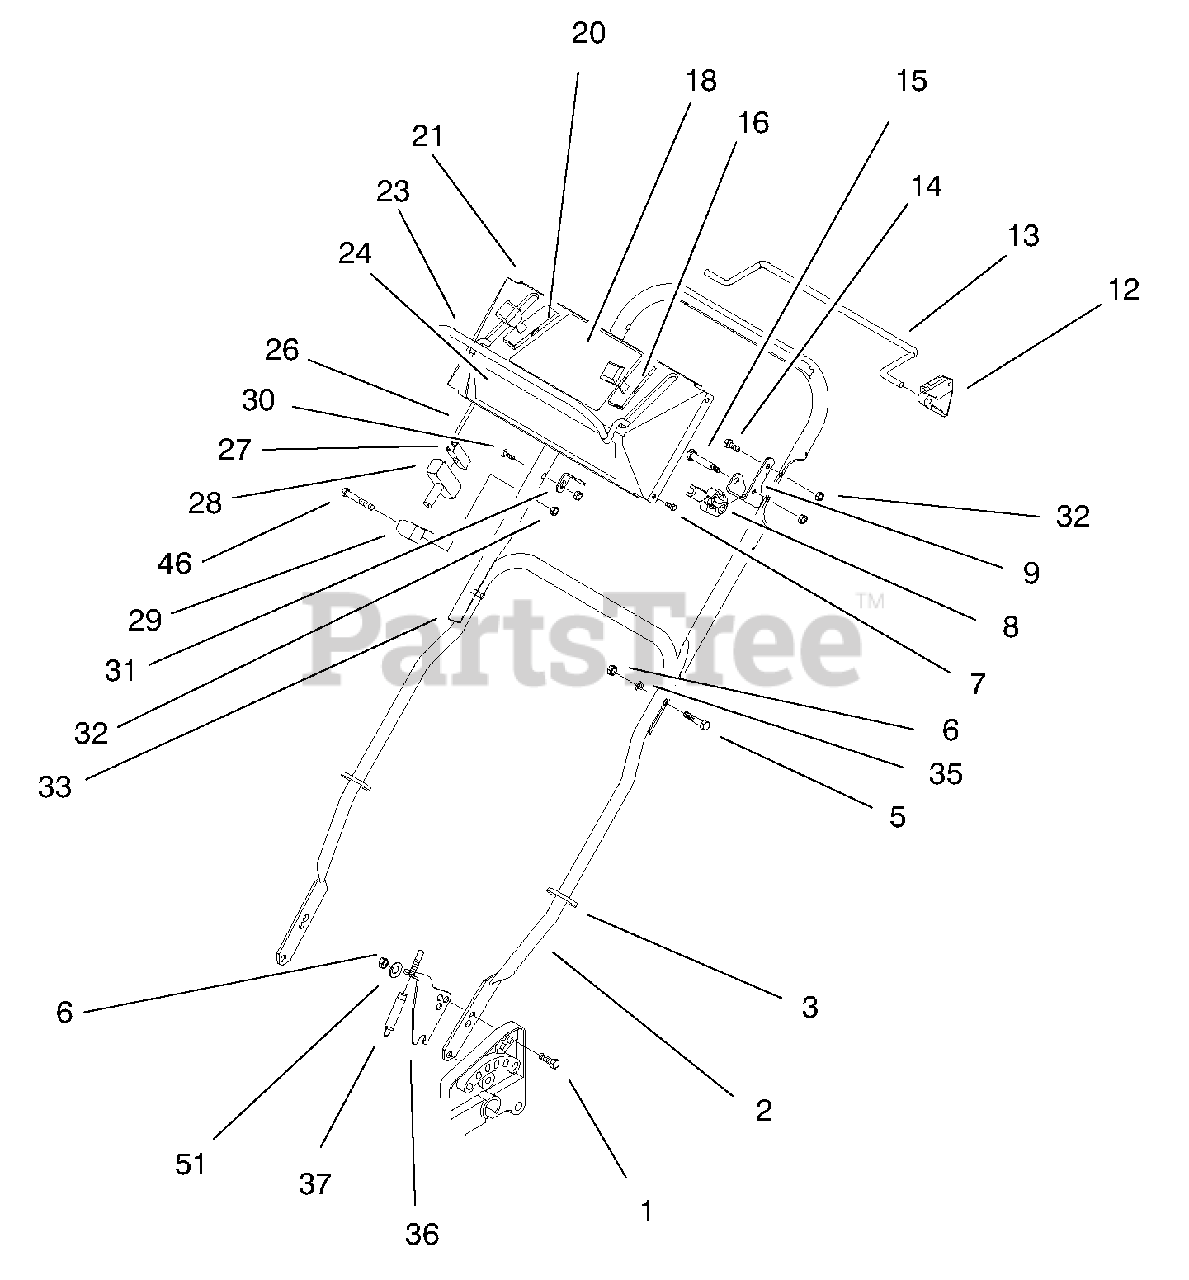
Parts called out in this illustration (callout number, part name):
1	Bolt-Carriage
2	Handle-Section Lower
3	Tie Strap
5	Screw-Hex Hd.
6	Nut-Lock
7	Screw-Phillips Hd.
8	Cam-Brake
9	Bracket-Bail Stop
12	Stop-Pivot
13	Bail-SP Control
14	Screw-Hex Hd. Cap
16	Cable-Throttle
18	Decal-Control Panel
20	Control-Speed Ground
21	Panel-Control (Incl. Ref. #18)
23	Bail-Engine Control
24	Decal-Console Front
26	Cable-Control
27	Clip-Rope Insert
28	Handle-Starter
29	Guide-Rope
30	Screw-Handle
31	Bracket-Cable Anchor
32	Nut-Lock
33	Handle-Upper
36	Bracket-Traction Cable
37	Cable-Traction
46	Screw-Hex Hd. Cap
49	Nut-Lock
51	Washer-Flat
